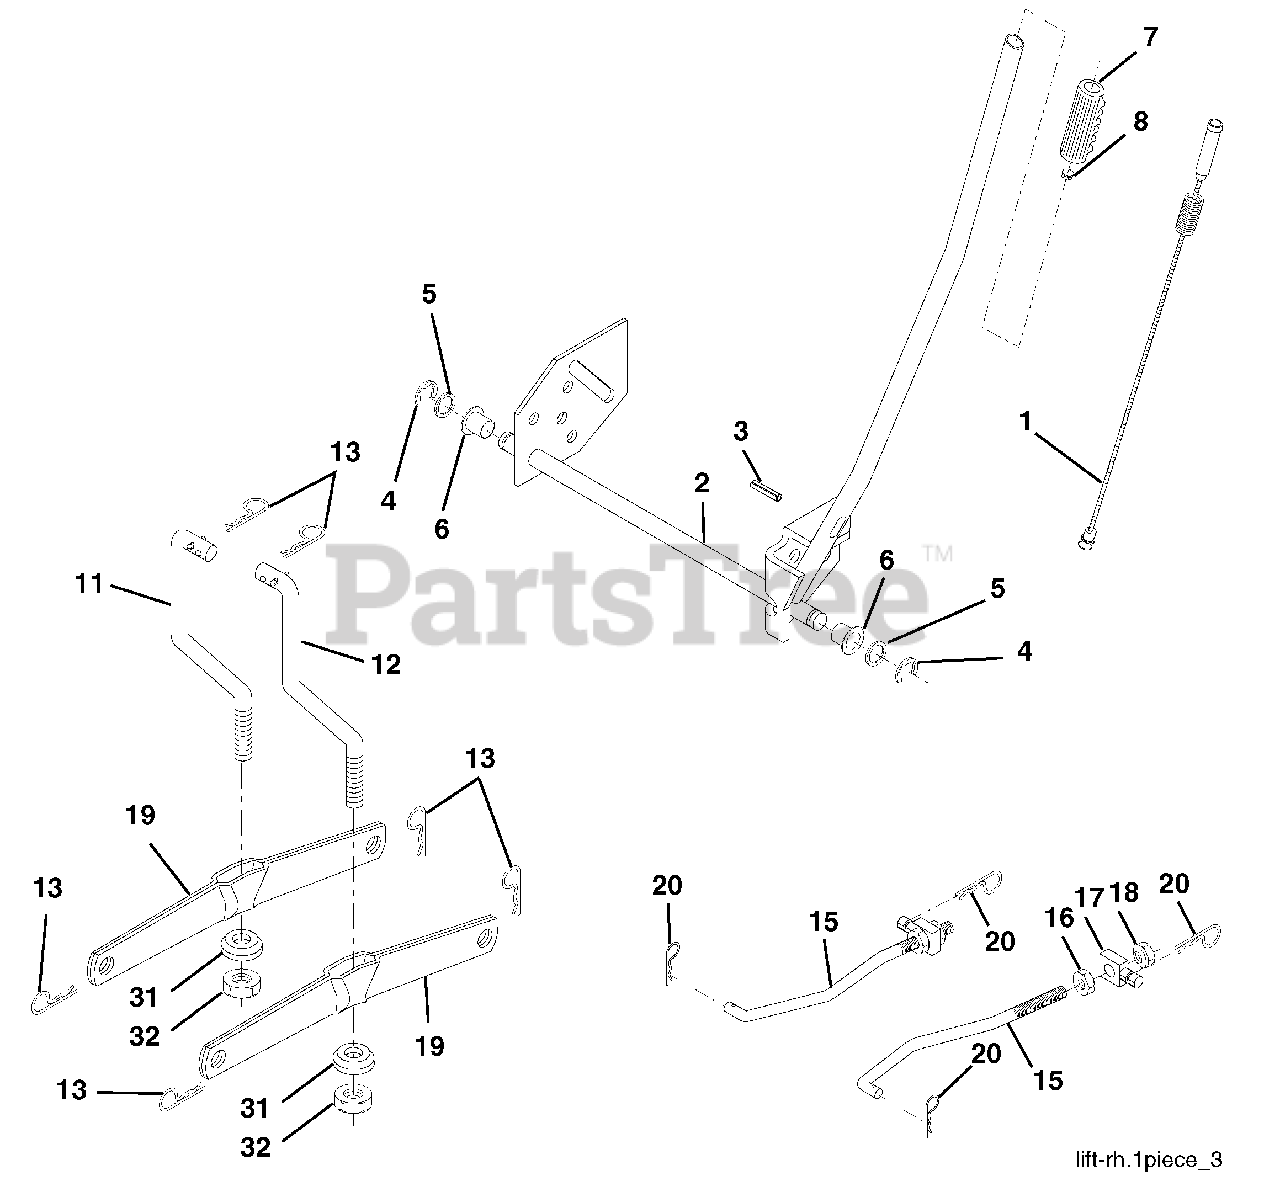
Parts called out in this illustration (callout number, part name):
1	Washer Asm Inner Spring W/Plunger
2	Shaft Asm. Lift
3	Pin Groove
4	E Ring #5133-62
5	Washer 21/32 x 1 x 21 Ga.
6	Bearing Nylong
7	Grip Handle Bicycle
8	Button Plunger Black
11	Link Asm Lift L.H.
12	Link Asm Lift R.H.
13	Retainer Spring
16	Nut Jam Hex 1/2-13 unc
17	Trunnion Blk Zinc
18	Nut Lock w/wsh 1/2-13 unc
19	Arm Suspension Mower
20	Retainer Spring
31	Bearing, Pvt. Lift.
32	Nut Crownlock 3/8-24
